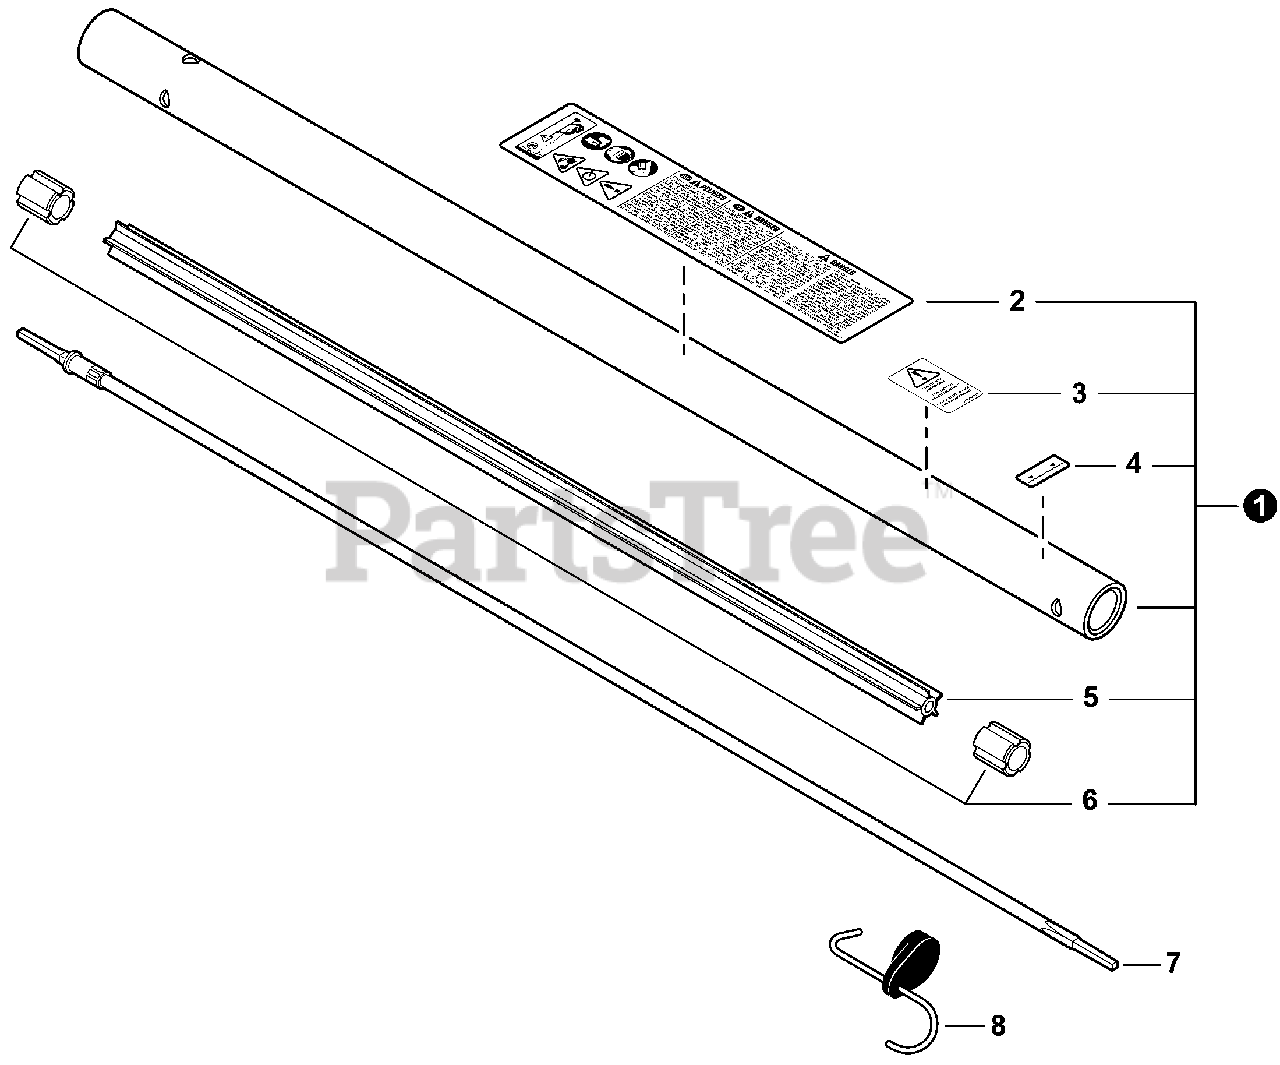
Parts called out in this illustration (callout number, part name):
1	MAIN PIPE ASSY
2	LABEL, CAUTION
3	LABEL, CAUTION - PAS-280
4	LABEL - ALIGNMENT
5	LINER - FLEXIBLE
7	DRIVESHAFT - FLEXIBLE
8	HANGER, ATTACHMENT
